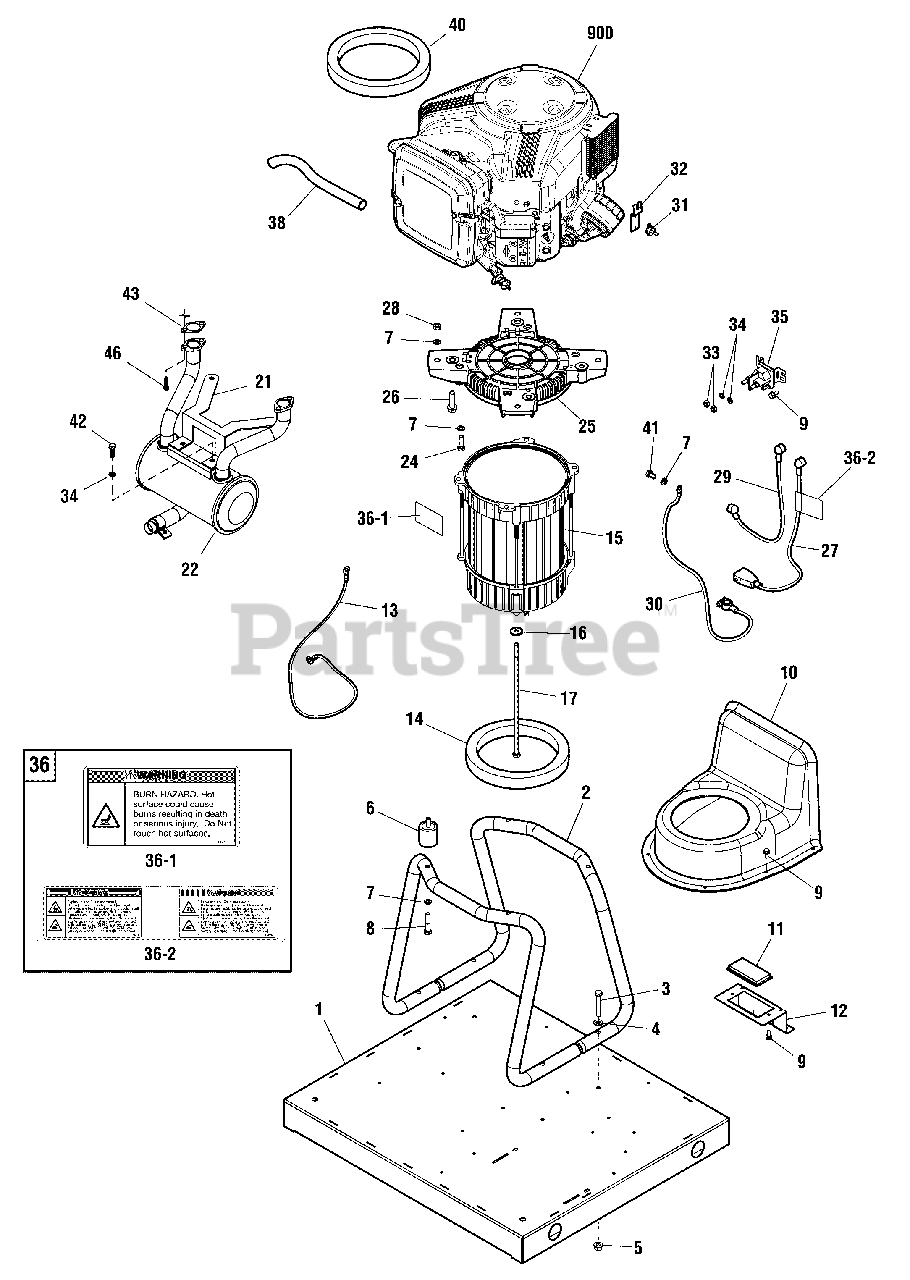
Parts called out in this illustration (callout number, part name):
3	* CAPSCREW, HEX HEAD, 5/16-18 x 2
4	* WASHER, FLAT, M8 (or 5/16)
5	* NUT-FLANGE, 5/16-18
6	MOUNT-VIBRATION
7	* WASHER, LOCK, M8 (or 5/16)
8	* CAPSCREW, HEX HEAD, M8-1.25 x 35
9	BOLT
11	REGULATOR-VOLTAGE
15	ALTERNATOR
21	BRACKET-MUFFLER
24	* CAPSCREW, HEX HEAD, 5/16-18 x 1
26	SCREW
27	WIRE
28	* NUT-HEX, M8-1.25
32	PLATE-TEMP SWITCH
33	* NUT-1/4-20
34	* WASHER, LOCK, M6 (or 1/4)
35	SOLENOID-STARTER
36	DECAL SHEET-WARNINGS
36-1	DECAL, Warning, Burn Hazard
36-2	DECAL, Warning, Explosion
41	* SCREW, M8-1.25 x 13
42	* CAPSCREW, HEX HEAD, M6 - 1 x 12
900	** ENGINE
